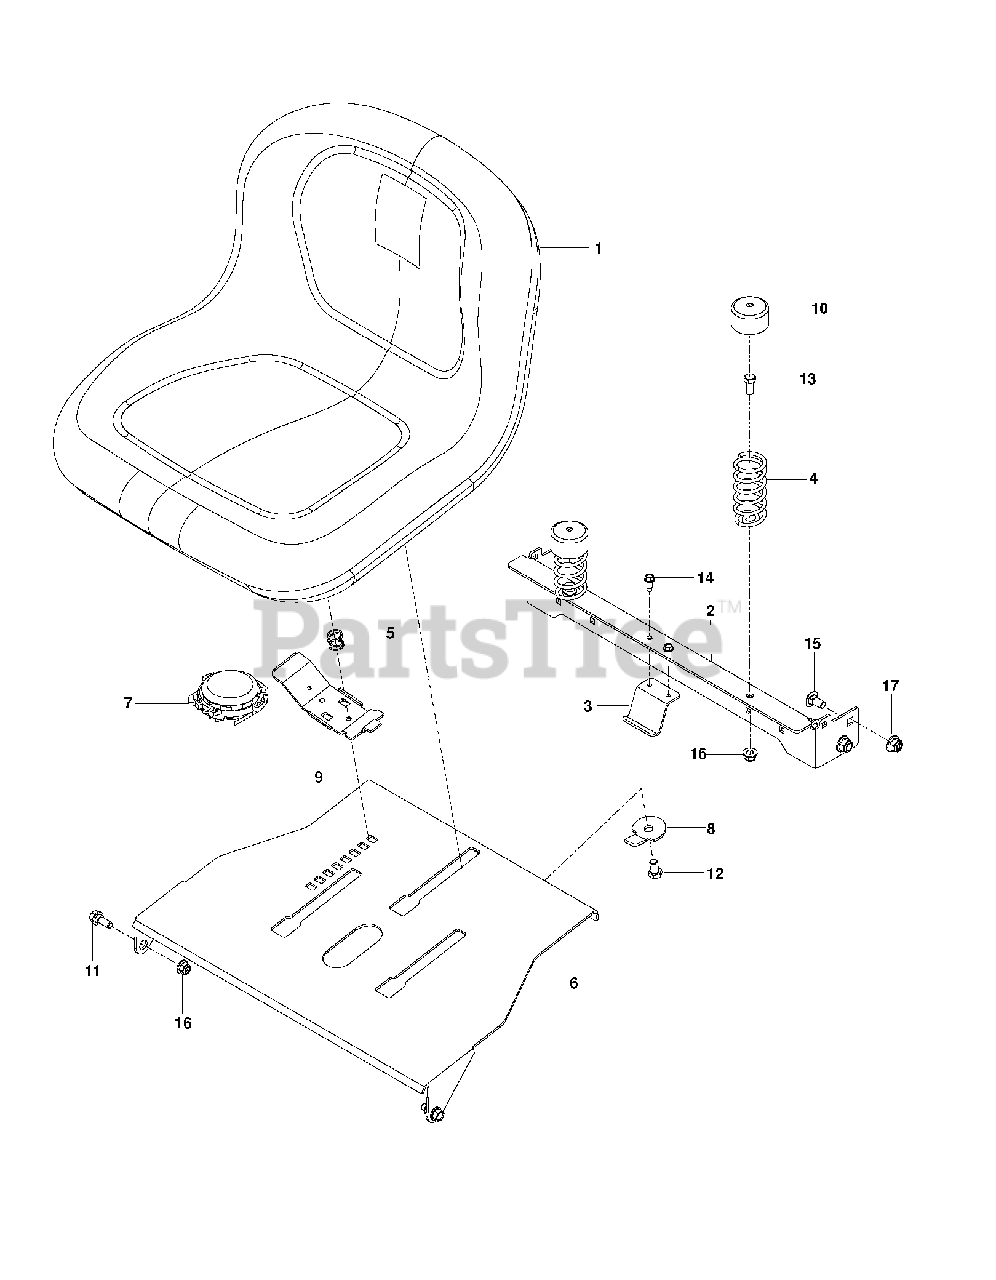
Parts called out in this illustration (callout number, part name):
1	SEAT.TG150.BLK.NLOGO.
2	SEAT SUPPORT, REAR, BLUE
3	HOLDING DEVICE, FUEL TANK, BLK
4	SEAT SPRING
5	SPRING.LATCH.SEAT.TEX
6	PLATE, SEAT, BLUE
7	SWITCH, SEAT N/C
8	STOP, SEAT, BLACK
9	HANDLE.SLIDE.SEAT.TEX.BLACK
10	SPRING CAP
11	BOLT, SHOULDER
12	HCS 3/8-16 X 5/8 GR 5 ZD
13	HCS 5/16C X 3/4
14	SCREW 1/4 X 5/8
15	RHSNB 3/8-16 X 3/4 GR5 ZD
16	5/16-18 NYLOC FLANGE NUT
17	NUT 3/8-16 HEX FLG NYLOC ZD
